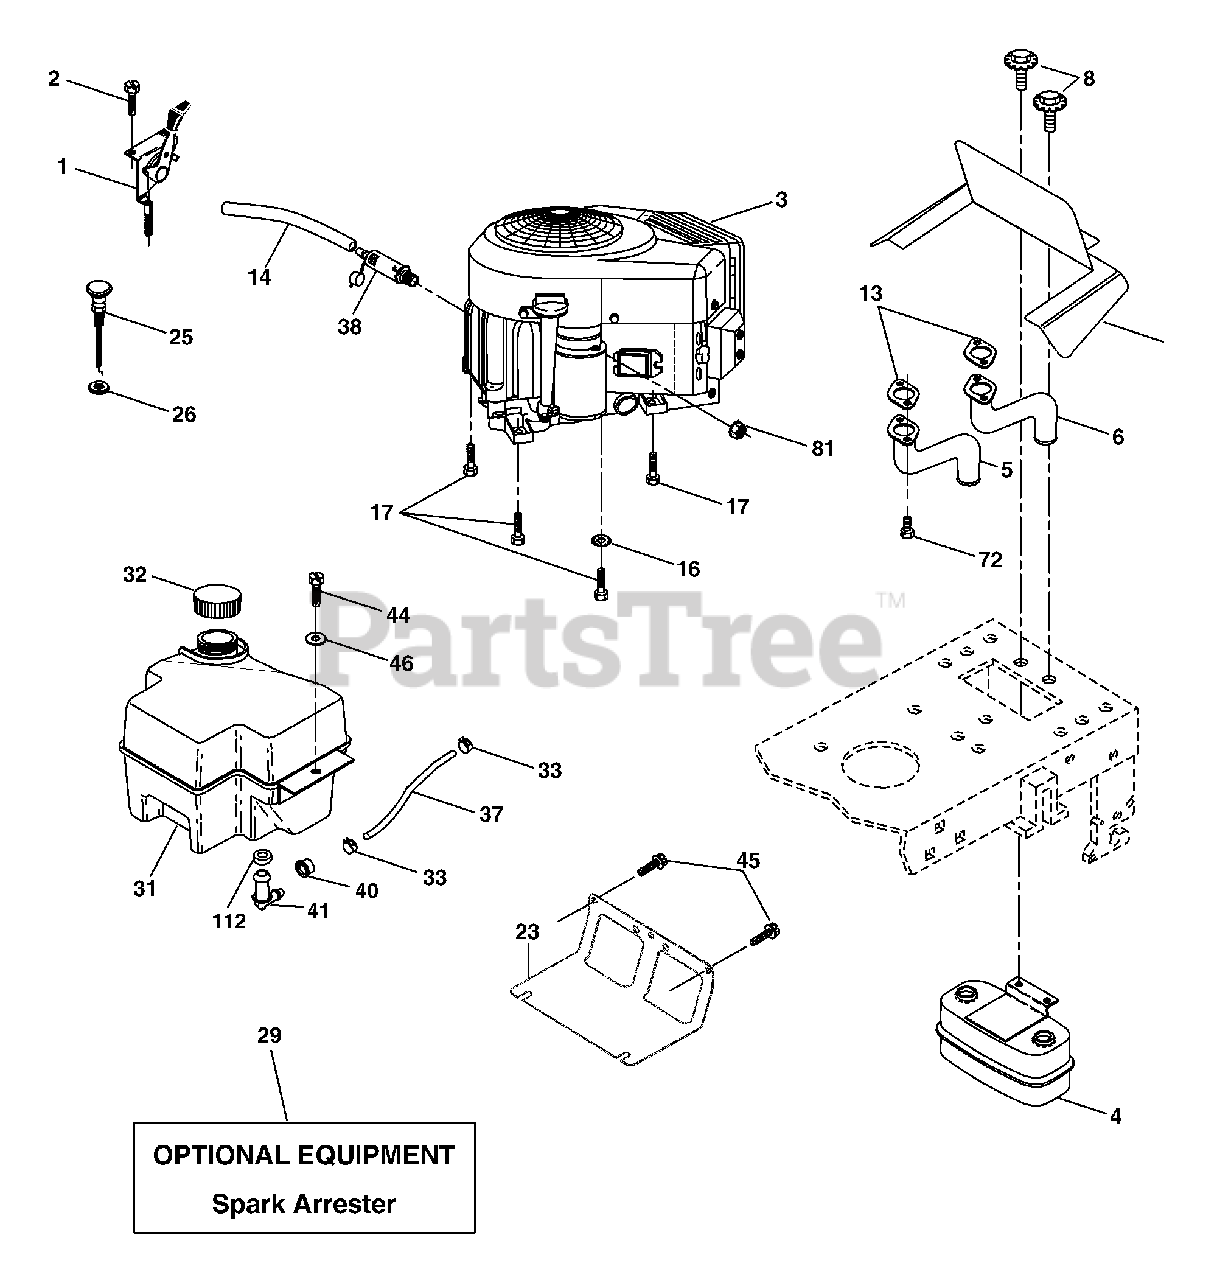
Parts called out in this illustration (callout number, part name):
1	Control, Throttle
2	Screw Hex Thd Cut 1/4-20 x 1/2
4	Muffl er, Asm. Twin Lo-Tone
5	Pipe Exhaust Intek 20 RH
6	Pipe Exhaust Intek 20 LH
8	Bolt 5/16-18 Unc x 3/4 w/Sems
10	Shield Browing B&S Untek II
13	Gasket Muffl er
14	Tube Drain Oil Easy
16	Washer Lock Ext Tooth 3/8
17	Screw 3/8-16 x 1-1/2
23	Shield Brn/Dbr Guard
26	Nut Keps 3/8-24 unf
29	Kit Spark Arrestor (Flat Scrn)
31	Tank, Fuel
32	Cap Asm Fuel W/sym Vented
33	Clamp Hose Black
37	Line Fuel 20"
38	Plug Drain Oil Easy
40	Bushing Snap Nyl Blk Fuel Line
41	Stem Tank Fuel
44	Screw Hexwsh Thdrol 1/4-20 x 3/4
45	Screw Hexwsh Thdr 3/8-16 x 3/4
46	Washer 9/32 x 7/8 x 16 Ga
62	Washer Lock Hvy Hlcl Spr 5/16
72	Screw Hex Hd Cap 5/16-18 x 3/4
81	Nut Keps Hex 1/4-20 Unc
112	Bushing
